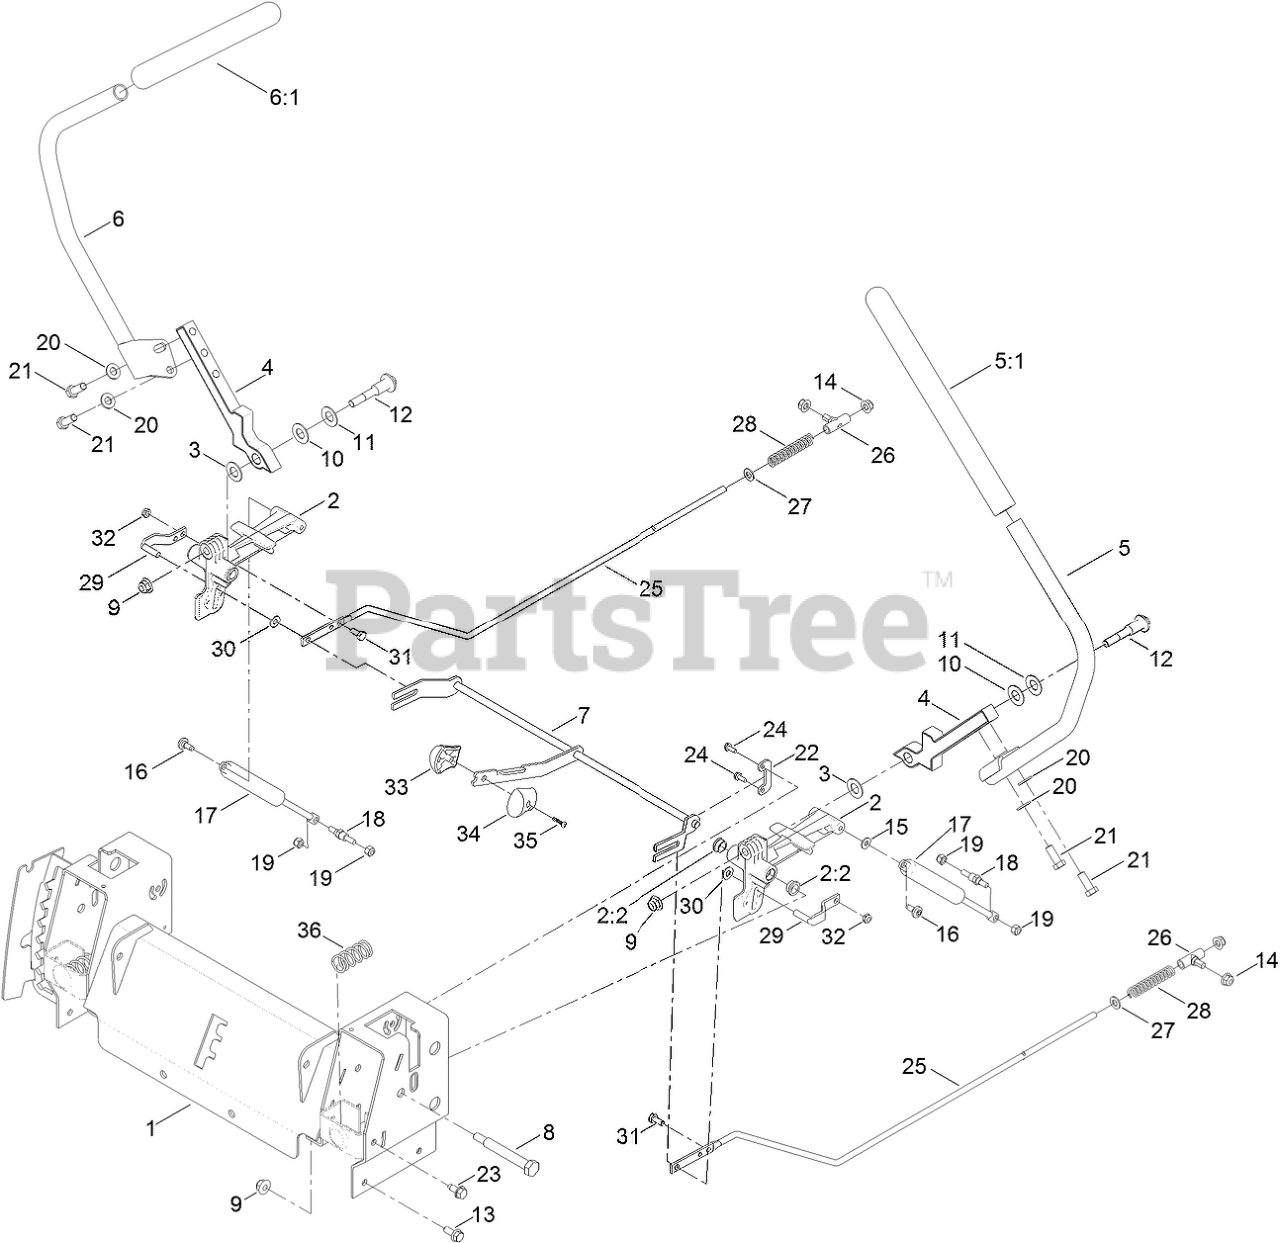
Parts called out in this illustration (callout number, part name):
1	CONTROL BOX ASM
2	ACTUATOR ARM ASM
2:2	BUSHING-FLANGE
3	WASHER-NYLON
4	ARM-CONTROL
5	HANDLE-CONTROL, LH
6	HANDLE-CONTROL, RH
7	SPEED CONTROL ASM
8	BOLT-PIVOT
9	NUT-HF, NI
10	WASHER
11	WASHER-BELLEVILLE
12	BOLT-PIVOT
13	SCREW-HHF
14	NUT-HF, NI
15	WASHER
16	SCREW-SHOULDER
17	DAMPER
18	STUD-DAMPER
19	NUT-LOCK, NI
20	WASHER-FLAT
21	SCREW-HH
22	RETAINER
23	SCREW-HWHTF
24	SCREW-TAPTITE
25	ROD-HYDRO
26	MOUNT-ROD, HYDRO
27	WASHER-PLAIN
28	SPRING-RETURN, NEUTRAL
29	PIN-ROD, HYDRO
30	SPACER-NYLON
31	SCREW-HH
32	NUT-LOCK, NI
33	KNOB-RH
34	KNOB-LH
35	SCREW-PPH
36	SPRING-RETURN
